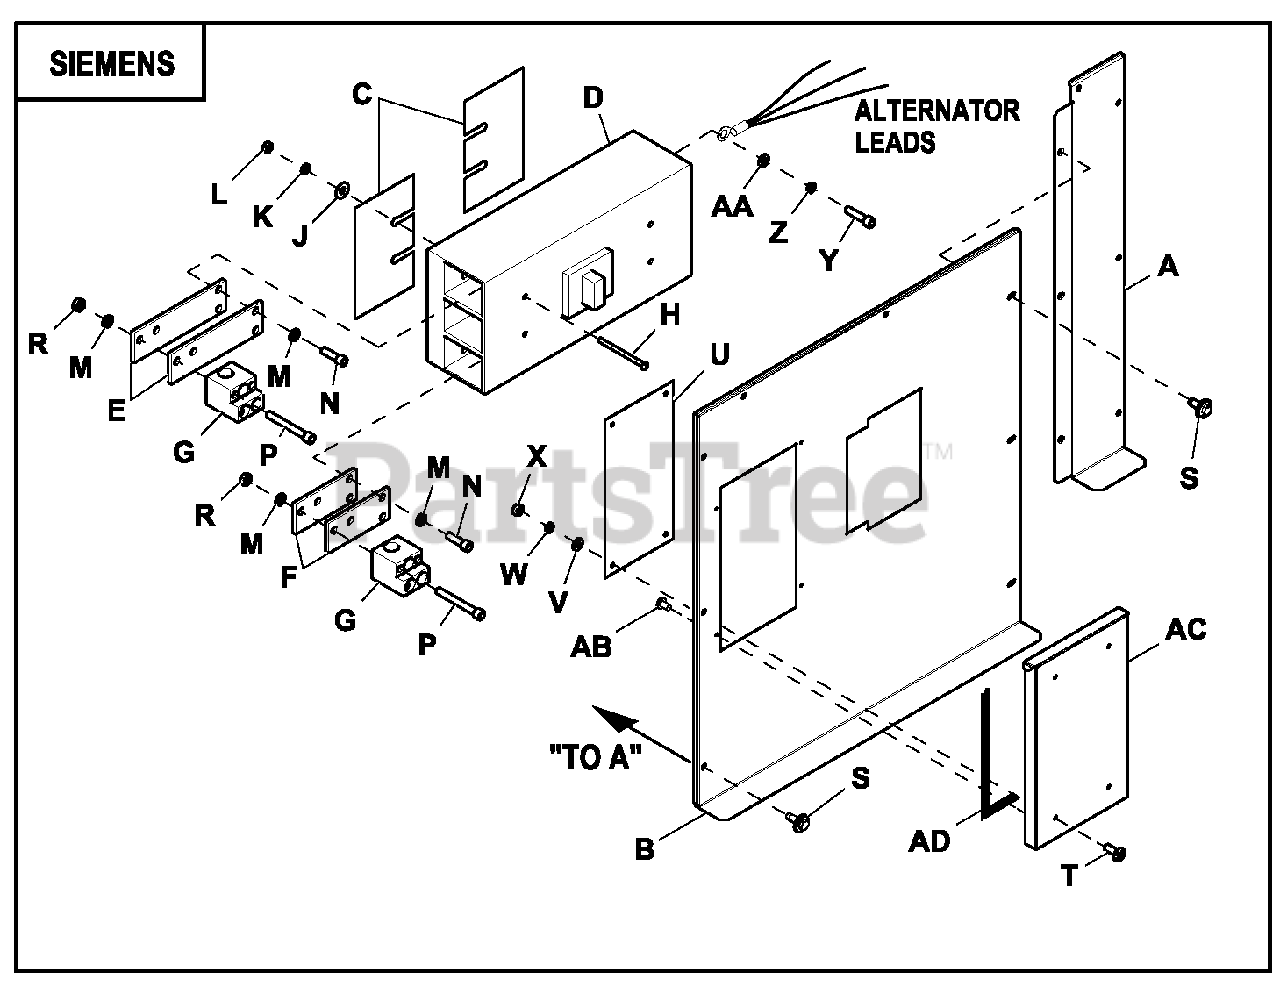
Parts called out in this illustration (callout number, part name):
63	TRIM VINYL BLACK 1/8GP (3"LG)
64	DECAL NE U TRAL
65	DECAL GRO U ND L U G
66	DECAL CA U TION ELEC SHOCK SM
A	COVER FIXED LMD CB
B	COVER SERVICE LMD CB W/B U MPOUT
C	INS U LATOR (NOMEX)
D	CB 0700A 3P 600V S LMD6 LL
E	B U S BAR 1/4X2 LMD L1
F	B U S BAR 1/4X2 LMD L1
G	L U G SIEMENS LMD/LD TA3K500
H	SCREW RHM 1/4-20X3-1/2
J	WASHER FLAT 1/4-M6 ZINC
K	WASHER LOCK M6-1/4
L	N U T HEX 1/4-20 STEEL
M	WASHER LOCK 3/8
N	SCREW SHC 3/8-16 X 1.25 G8.8 Z
P	SCREW SHC 3 /8 -1 6X 3 .0 BLK OX
R	N U T HEX 3/8-16 STEEL
S	SCREW HWHT M6-1 X 16 N WA Z/JS
T	SCREW PHTT M4-0.7 X 10 ZP
U	INS U L CB COVER
V	WASHER FLAT M4
W	WASHER LOCK+8-M4
X	N U T HEX M4-0.7 G8 YEL CHR
Y	SCREW SHC 3/8-16X1 G8.8NZ
AA	WASHER FLAT .406ID X 1.62OD
AB	RIVET POP .125 X 0.337 STEEL
AC	COVER B U MP O U T SERVICE LMD CB
AD	STRIP SEALANT 1/8X1 (36"LG)
